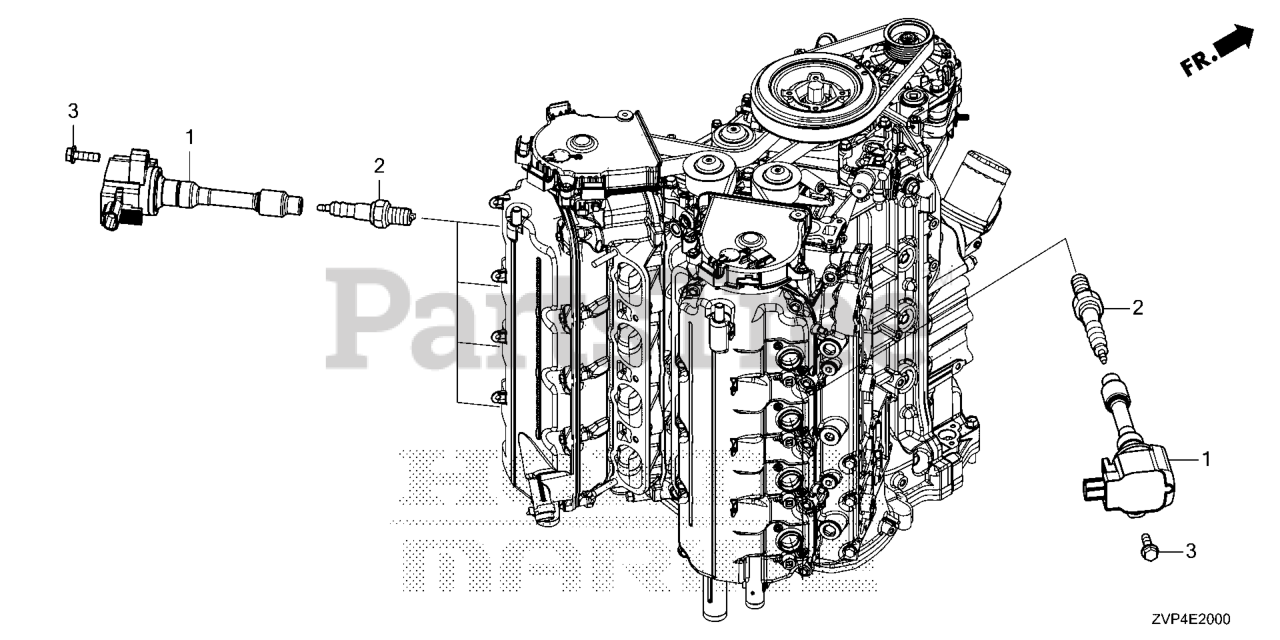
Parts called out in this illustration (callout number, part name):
1	COIL ASSY., PLUG TOP
2	S/PLG (LZKAR7F11E)
2	S/PLG (ILZKAR7S11E)
3	BOLT, FLANGE (6X20)
